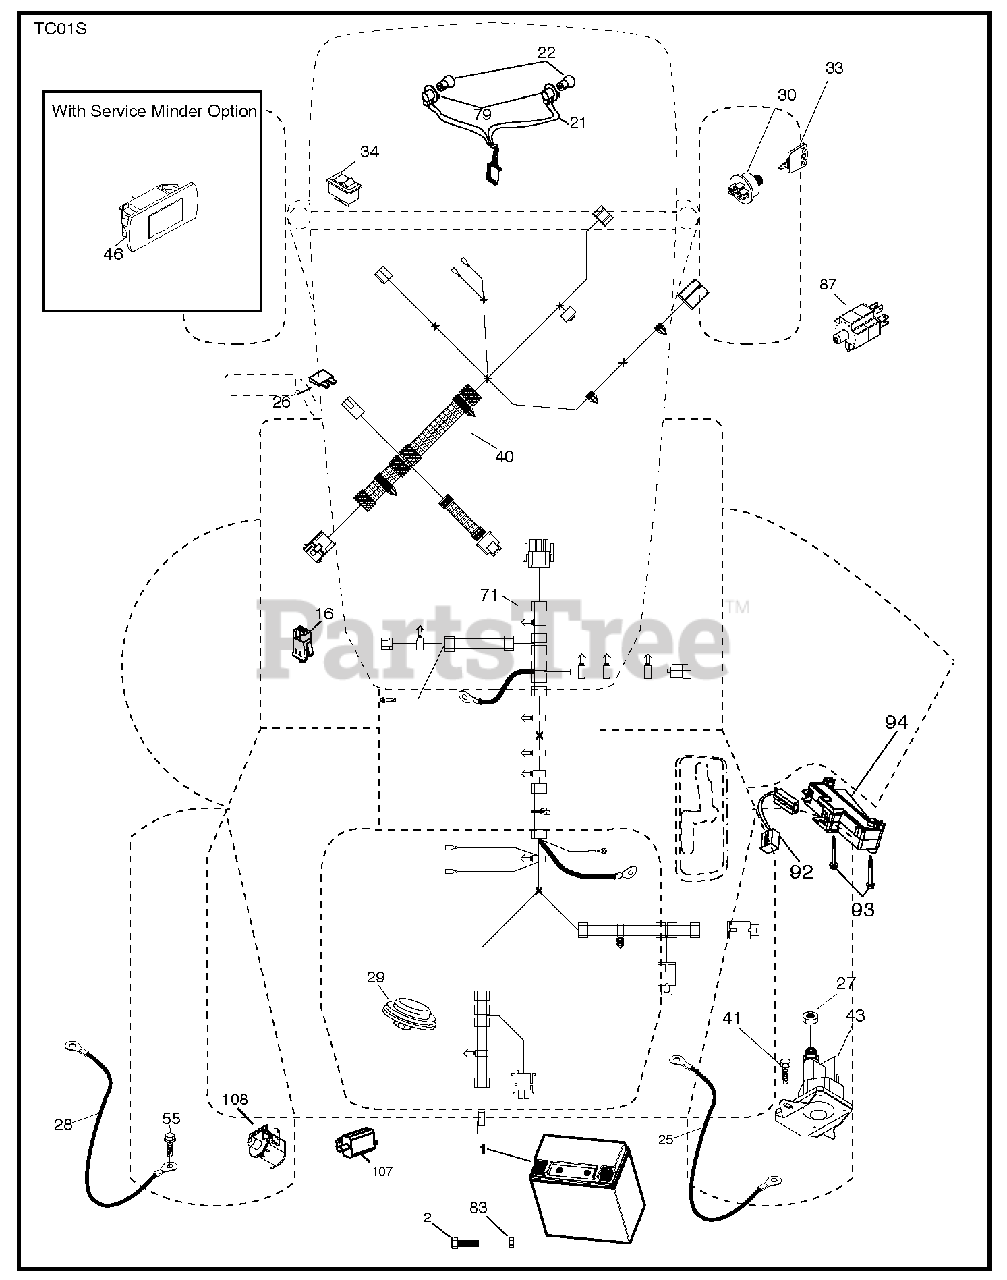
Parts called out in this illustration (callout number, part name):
16	SWITCH INTERLOOK PUSH-IN
21	HARNESS.LIGHT W/4152J BULBS
22	LIGHTBULB
26	FUSE 20AMP
27	NUT
29	SWITCH.SEAT.DELTA.OPC.
30	SWITCH.IGN.DELTA.W.LGH.ROS
33	KEY.CHAIN.BLISTER.PACK.GEN.INT
34	SWITCH LT
41	SCREW
43	SOLENOID.W/BRASS.PLUNG
55	SCREW 5/16"
79	BULB HOLDER ASM.
92	HARNESS.PIGTAIL.CONSLE
93	SCREW.PLASTITE
94	MODULE.REVERSE.ROS
108	SWITCH.SNAPMOUNT.NC
